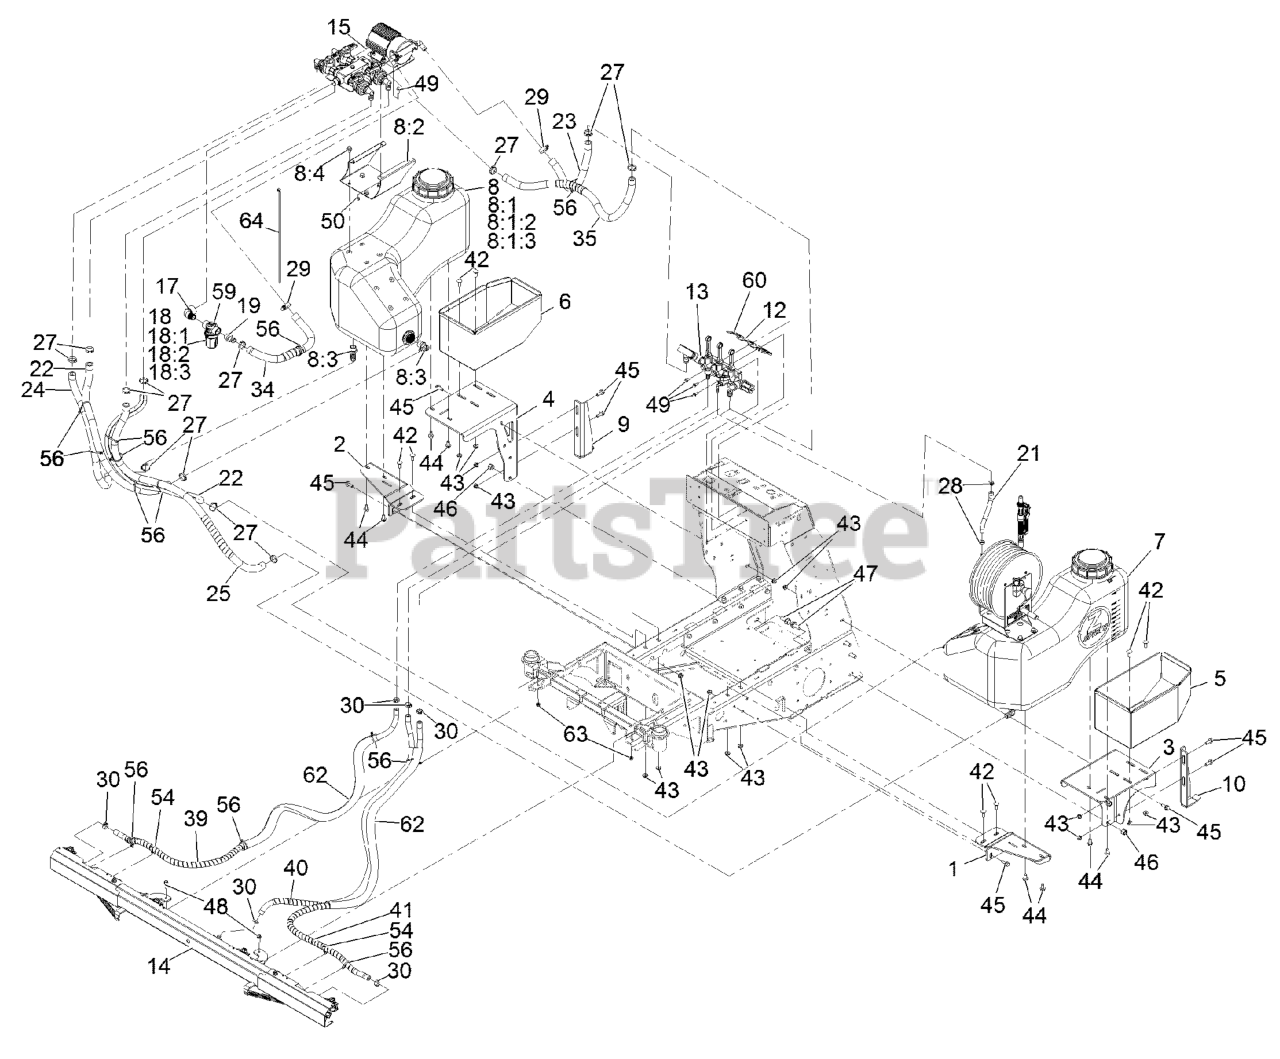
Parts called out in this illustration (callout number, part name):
1	Mount-Tank, LH Wing
2	Mount-Tank, RH Wing
3	Mount-Box, Lt Fert
4	Mount-Box, Rt Fert
5	BOX-FERT, LT
6	Box-Fert, Rt
7	ASM-Tank, Hose Reel
8	ASM-Tank, Rt
8:1	ASM-TANK, RT
8:1:2	CAP-TANK, SPRAY
8:1:3	FITTING-BULKHEAD
8:2	FITTING-ELBOW, 90
8:3	PLATFORM, LIQUID VALVE MO
8:4	Screw-HHF
9	Bracket-Anti-Tip, Rt
10	Bracket-Anti-Tip, Lt
12	BRACKET-MANIFOLD
13	ASM-Manifold
14	ASM, Boom
15	ASM, Liquid Valve
17	ELBOW-90DEG
18	STRAINER-INLINE
18:1	BOWL-STRAINER
18:2	GASKET-HEAD, LINE STRAINE
18:3	Screen-Strainer, 50 Mesh
19	HOSEBARB
21	Hose-Spray
22	Hose-Spray
23	Hose-Spray
24	Hose-Spray
25	Hose-Spray, Wrapped
27	Clamp-Oetiker, 167
28	CLAMP-OETIKER, 167
29	CLAMP-HOSE
30	CLAMP-OETIKER, 167
34	Hose-Spray, Wrapped
35	Hose-Spray, Wrapped
39	Hose-Spray, Wrapped
40	Hose-Spray, Wrapped
41	Hose-Spray, Wrapped
42	SCREW-CARR
43	Nut-Hex Flange
44	SCREW-HHF
45	SCREW-HHF
46	Nut,1/2-13,NYL INS,ST/ST,18-8
47	SCREW-HHF
48	SCREW-HHF
49	Screw-HHF
50	Nut-Hex Flange
54	CLIP-TIE
56	TIE-CABLE
59	DECAL-CAP, STRAINER
60	Decal-Valve, Boom
62	Guard-Mesh
63	Nut-Hex Flange
64	TIE-CABLE
